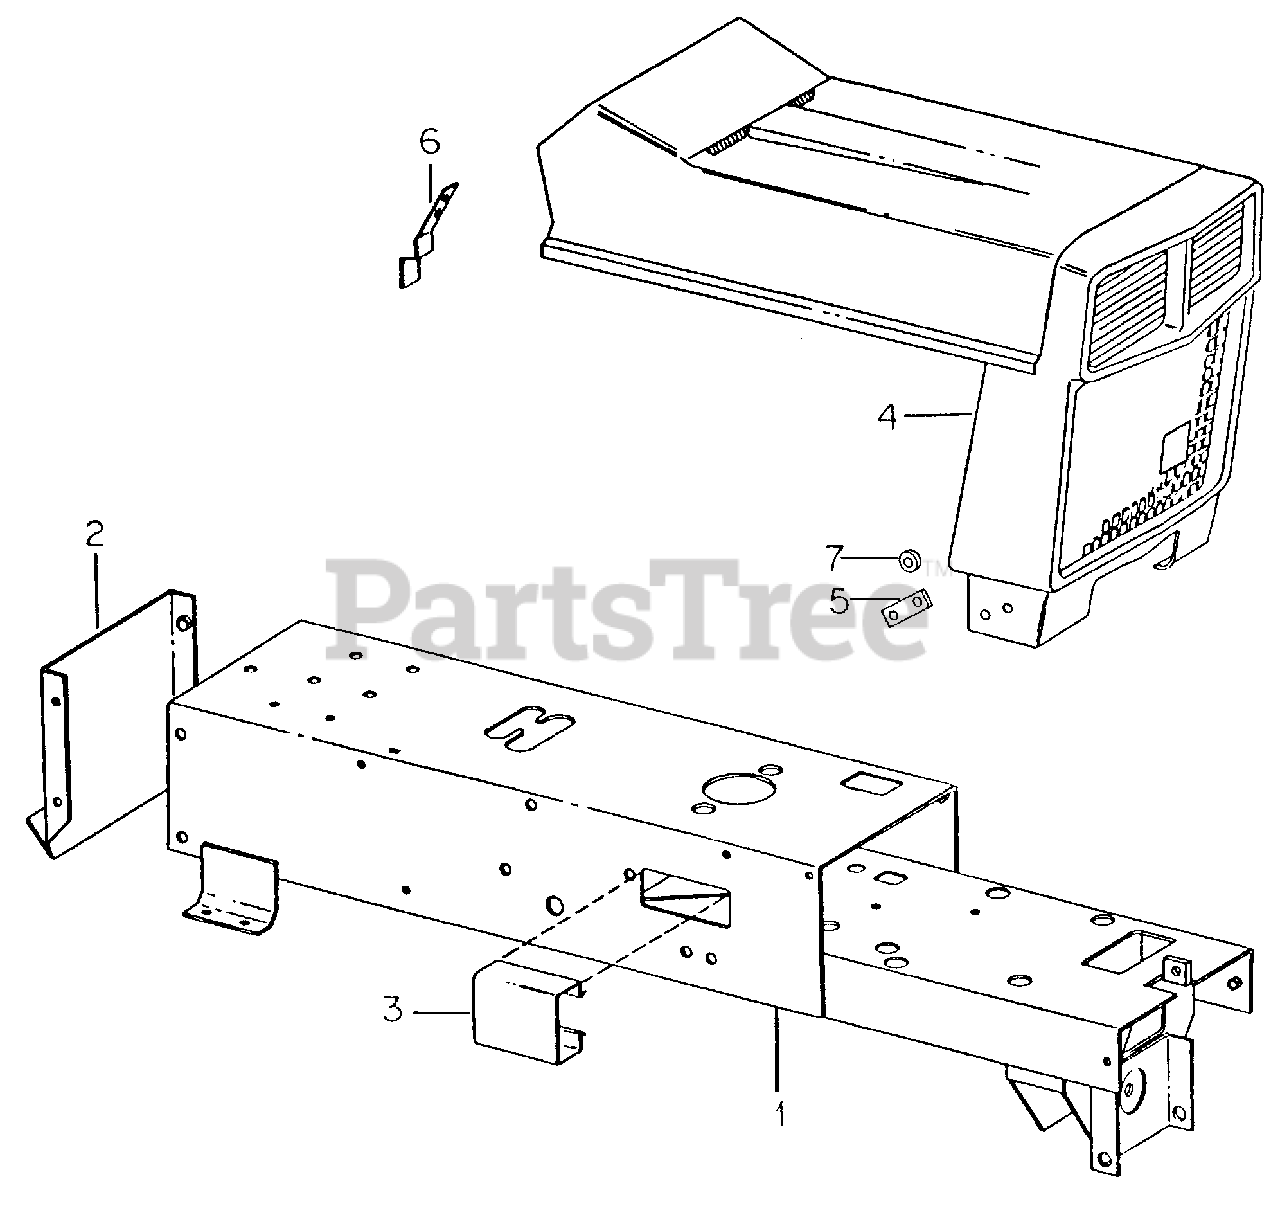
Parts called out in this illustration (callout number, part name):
1	Frame Assy
2	Drawbar Assy
3	Cover, Steering Arm
4	Hood Assy
5	Bracket, Hood Front Mounting
6	Latch, Hood
7	Spacer, Rubber
